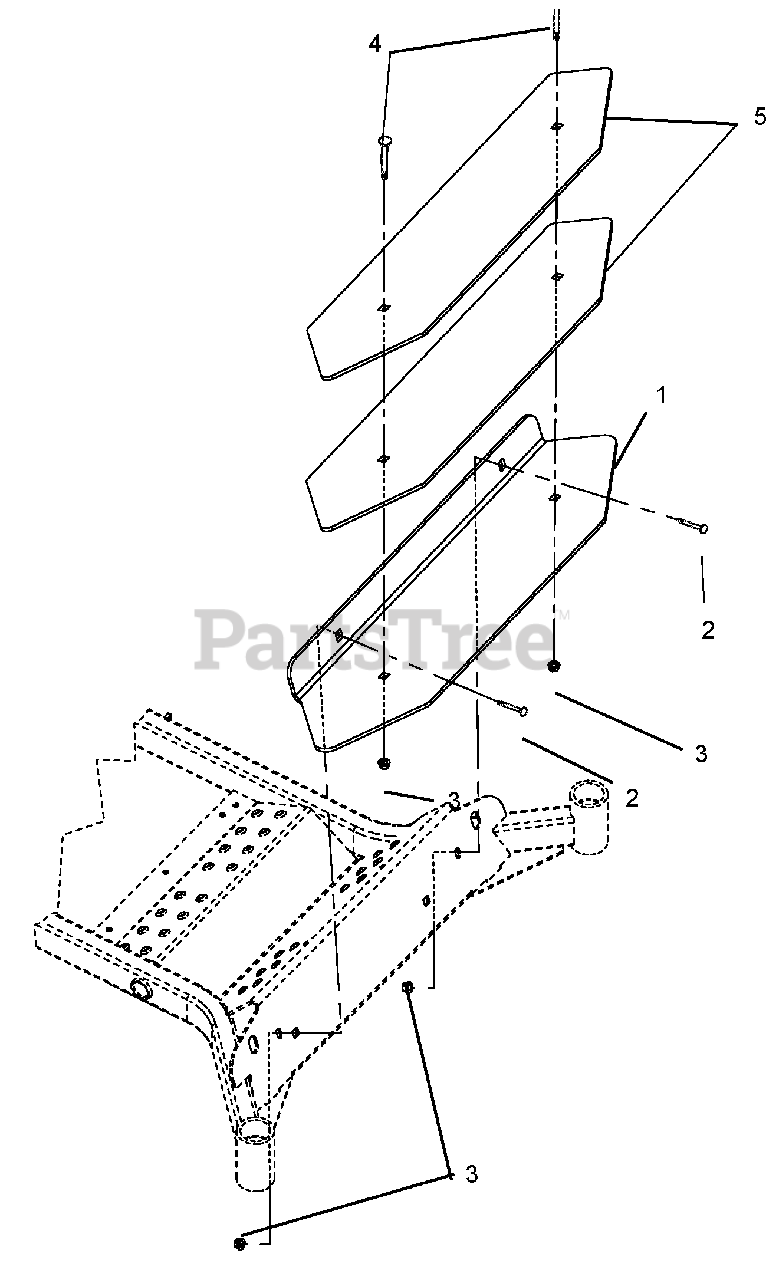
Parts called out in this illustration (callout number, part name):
1	Bracket, 100i Counterweight
2	Bolt, Round Head Square Neck .50-13 x 1.25 Grade 5
3	Nut, Locking-Top-Flange .50-13
4	Bolt, Round Head Square Neck .50-13 x 1.50 Grade 5
5	Counterweight, 100i
